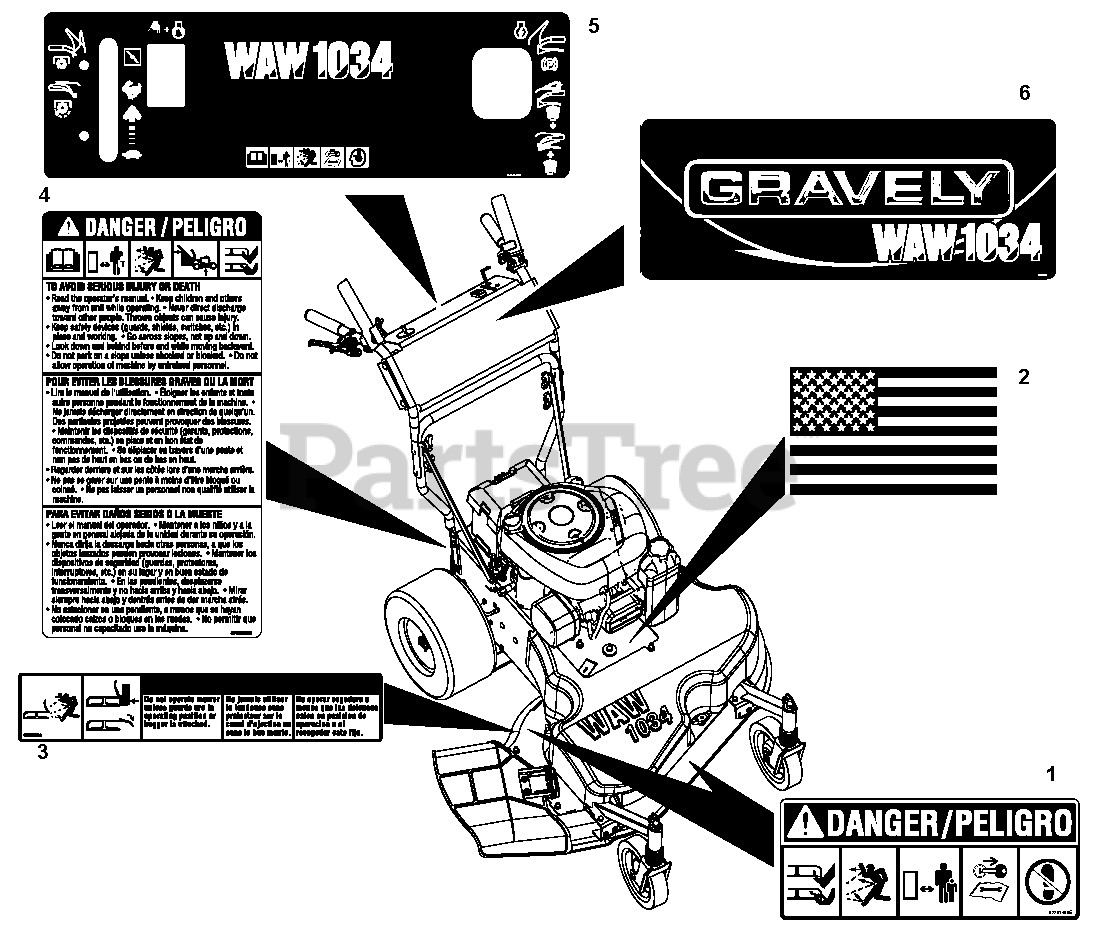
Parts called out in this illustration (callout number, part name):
1	Decal, Mower Pan Head Danger
2	Decal, American Flag
3	Decal, Warning
4	Decal, Bilingual Danger
5	Decal, WAW Operational
6	Decal, WAW 1034 Ariens Dash
